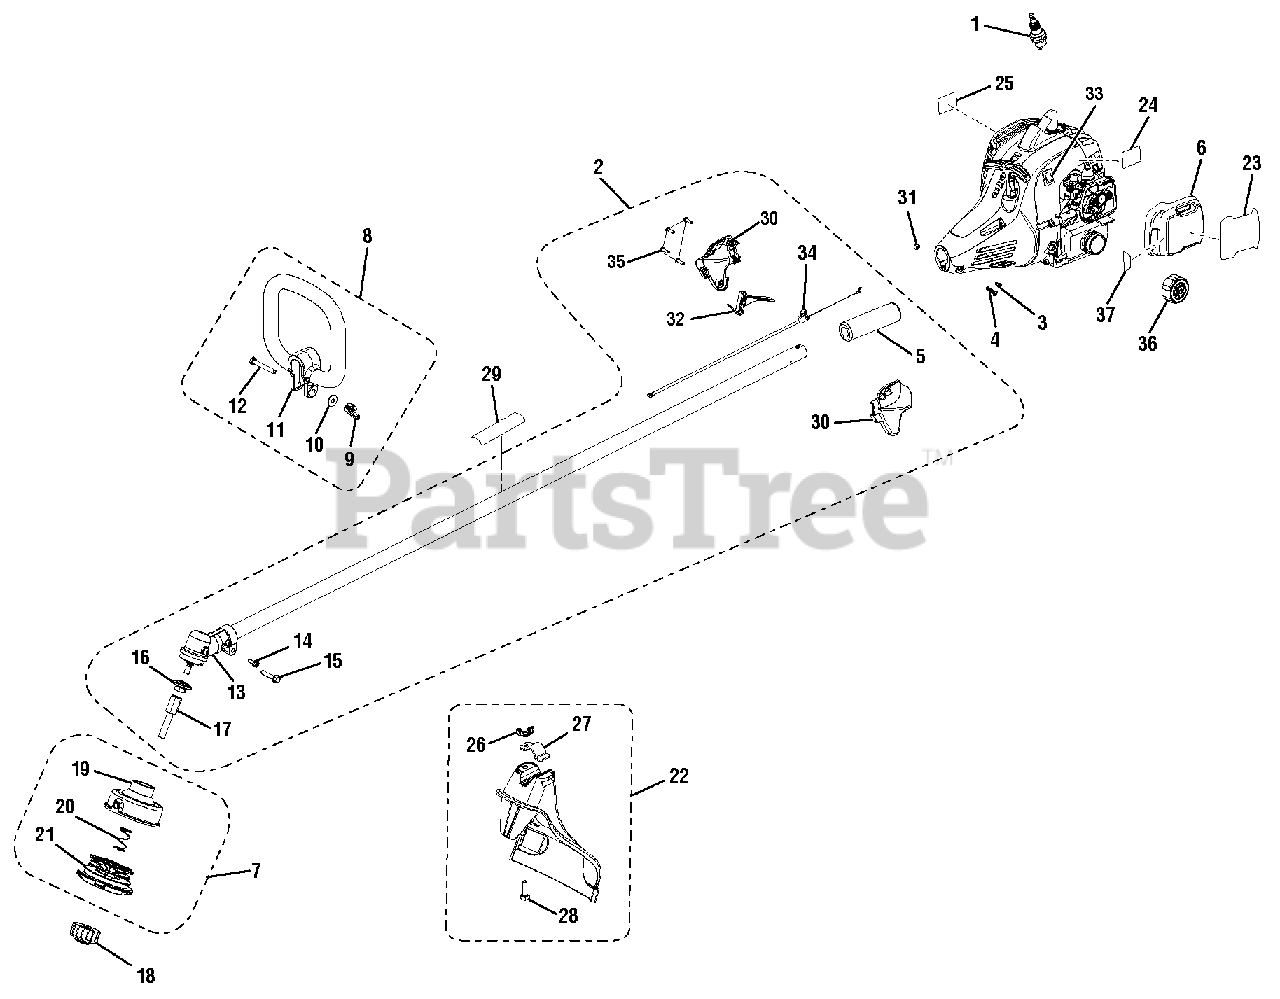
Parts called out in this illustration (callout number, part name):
1	Spark Plug (Champion RCJ6Y)
2	Boom Assembly
3	Screw (8-16 x 5/16 in.)
4	Screw (M6 x 20 mm)
5	Foam Grip
6	Air Box Cover
7	String Head Assembly
8	Front Handle Assembly
9	Wing Nut (1/4-20)
11	Front Handle
12	Bolt (1/4-20 x 2 in.)
13	Gear Head
14	Screw (10-25 x 5/16 in.)
15	Screw (1/4-20 x 1.25 in.)
16	Flange Washer
17	Adaptor
18	Spool Retainer
19	String Head Housing
20	Spring
21	Spool
22	Grass Deflector Assembly
23	Starting Label
24	Model Label (26SS)
25	Combustion Warning Label
26	Wing Nut (1/4-20)
28	Bolt (Square Head)
29	Icon Warning Label
30	Handle Assembly
31	Hex Nut (M6)
32	Throttle Trigger
33	Switch
34	Throttle Cable
35	Screw (M4 x 20 mm)
37	Throttle Label
